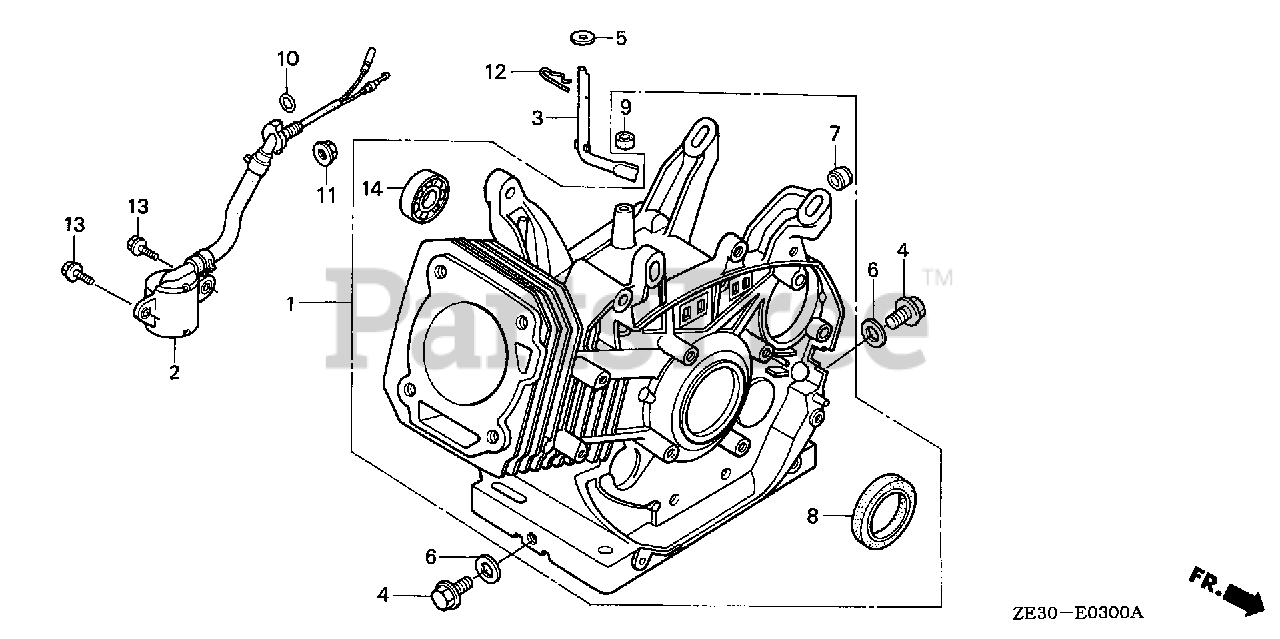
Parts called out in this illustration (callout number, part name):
1	CYLINDER ASSY. (STD)
3	SHAFT, GOVERNOR ARM
4	BOLT, DRAIN PLUG (12X15)
5	WASHER (8.2X17X0.8)
6	WASHER, DRAIN PLUG (12MM)
7	PLUG, SEALING (RUBBER 10MM)
8	OIL SEAL (35X52X8)
9	OIL SEAL (8X14X5)
12	PIN, LOCK (8MM)
14	BEARING, RADIAL BALL (6202)
